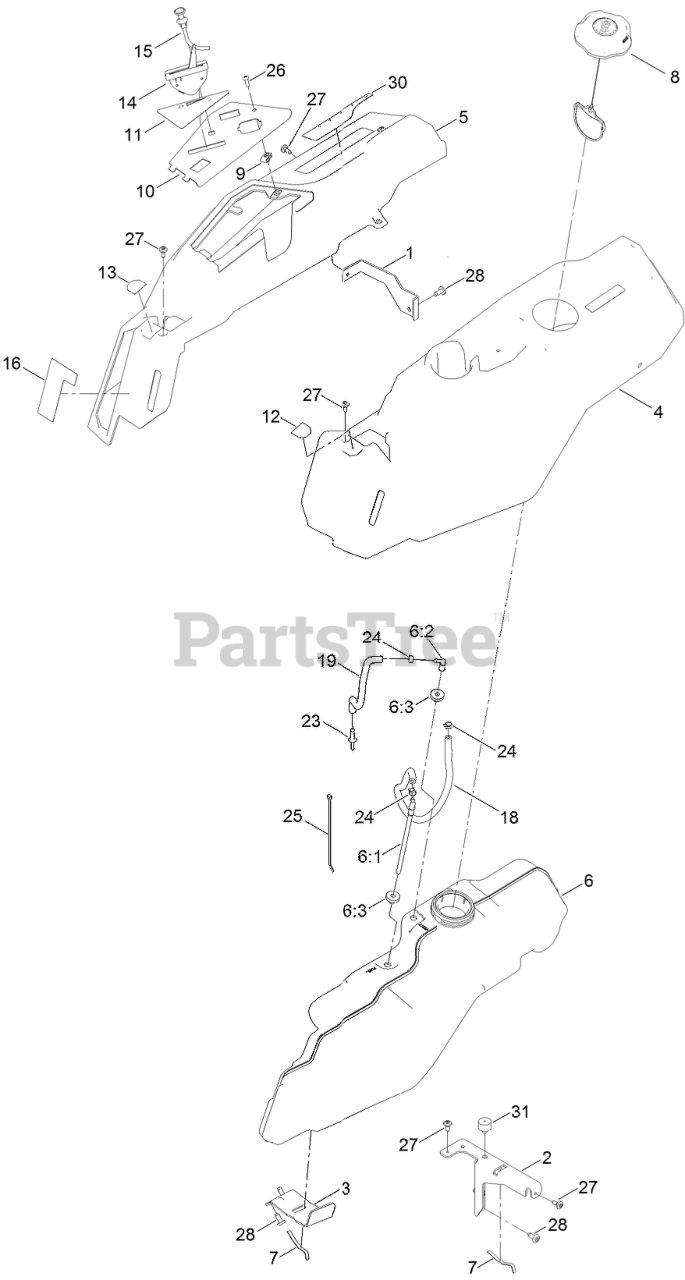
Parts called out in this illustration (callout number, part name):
1	BRACKET-POD
2	SUPPORT-POD, LH
3	SUPPORT-TANK, FUEL
4	POD-LH
5	POD-RH, MYRIDE
6	FUEL TANK ASM
6:1	CONNECTOR-ELBOW, 90 DEG
6:2	FITTING-PLASTIC
6:3	BUSHING
7	SPRING
8	CAP-FUEL, RATCHETING
10	PANEL-CONTROL
11	DECAL-PANEL, CONTROL
12	DECAL-CONTROL LEVER, LH
13	DECAL-CONTROL LEVER, RH
14	CABLE-THROTTLE
15	CABLE-CHOKE
16	DECAL-SMART SPEED
18	HOSE-FUEL
19	HOSE-FUEL
23	ADAPTOR-ORIFICE
24	CLAMP-HOSE
25	TIE-CABLE
26	SCREW-PRH
27	SCREW-SHOULDER
30	DECAL-ADJUSTMENT
31	BUMPER-GROMMET
